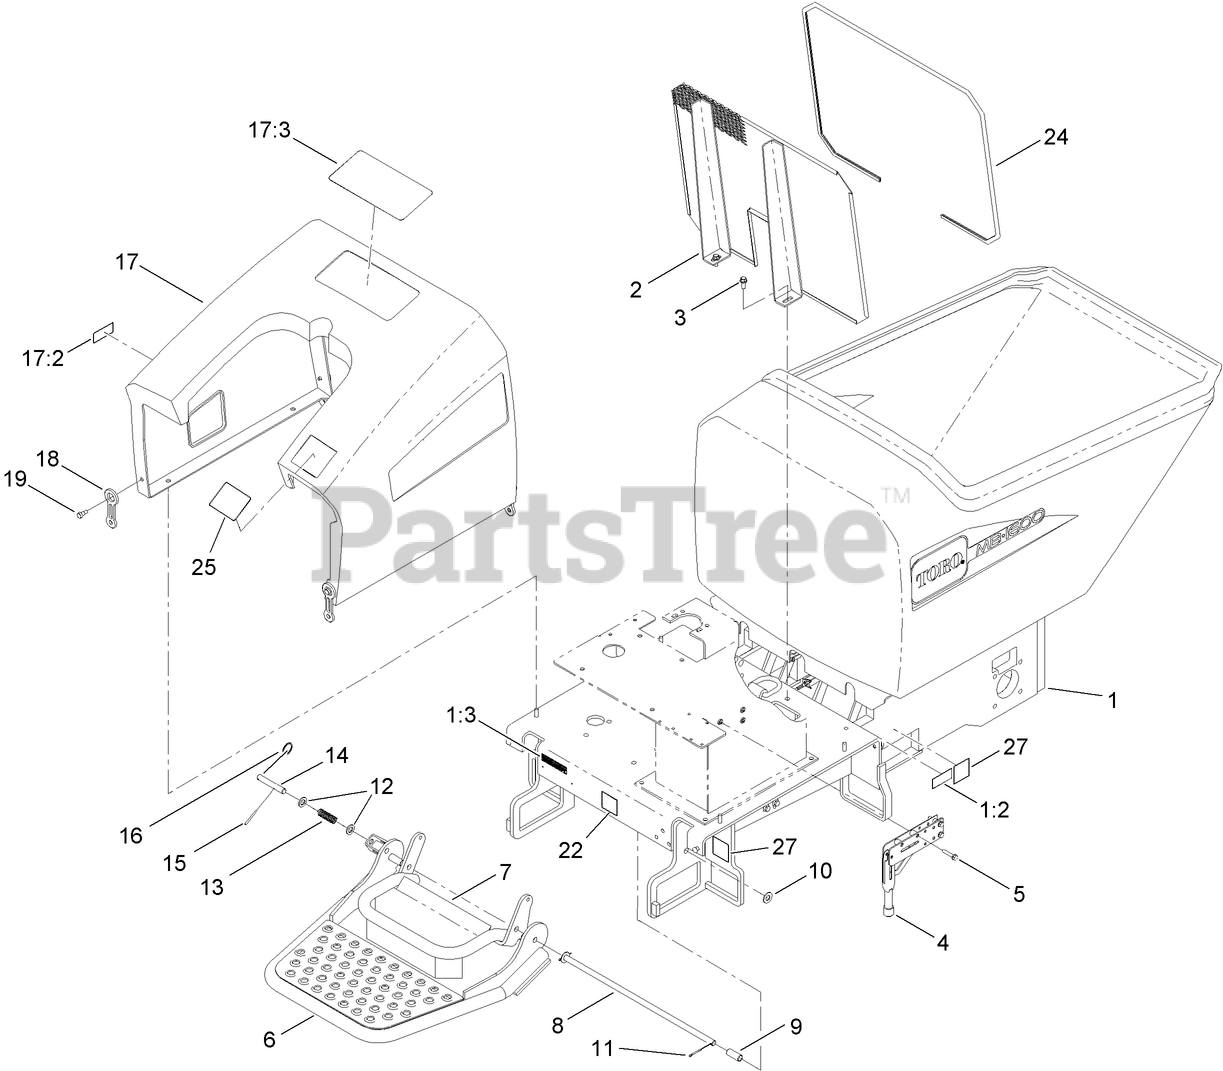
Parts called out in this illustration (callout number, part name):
1	MAIN FRAME ASM
1:2	DECAL-WARNING, CRUSHING
1:3	DECAL-ARRESTER, SPARK
2	GUARD-SPLASH
3	SCREW-HHF
4	LEVER
5	SCREW-HHF
6	STEP-PLATFORM
7	PEDAL-BRAKE
8	SHAFT-PIVOT, STEP
9	SPACER-BRAKE
10	WASHER-FLAT
11	PIN-COTTER
12	WASHER-FLAT
13	SPRING-COMPRESSION
14	PIN-LOCKOUT, STEP
16	RING-SPLIT
17	ENGINE COWL ASM
17:2	DECAL-SURFACE, HOT
17:3	DECAL-WARNING
18	LATCH-RUBBER
19	SCREW-HSBH
22	DECAL-BRAKE PEDAL
24	TRIM-SPLASH GUARD
25	DECAL-DUMP
27	DECAL-LIFT HERE
